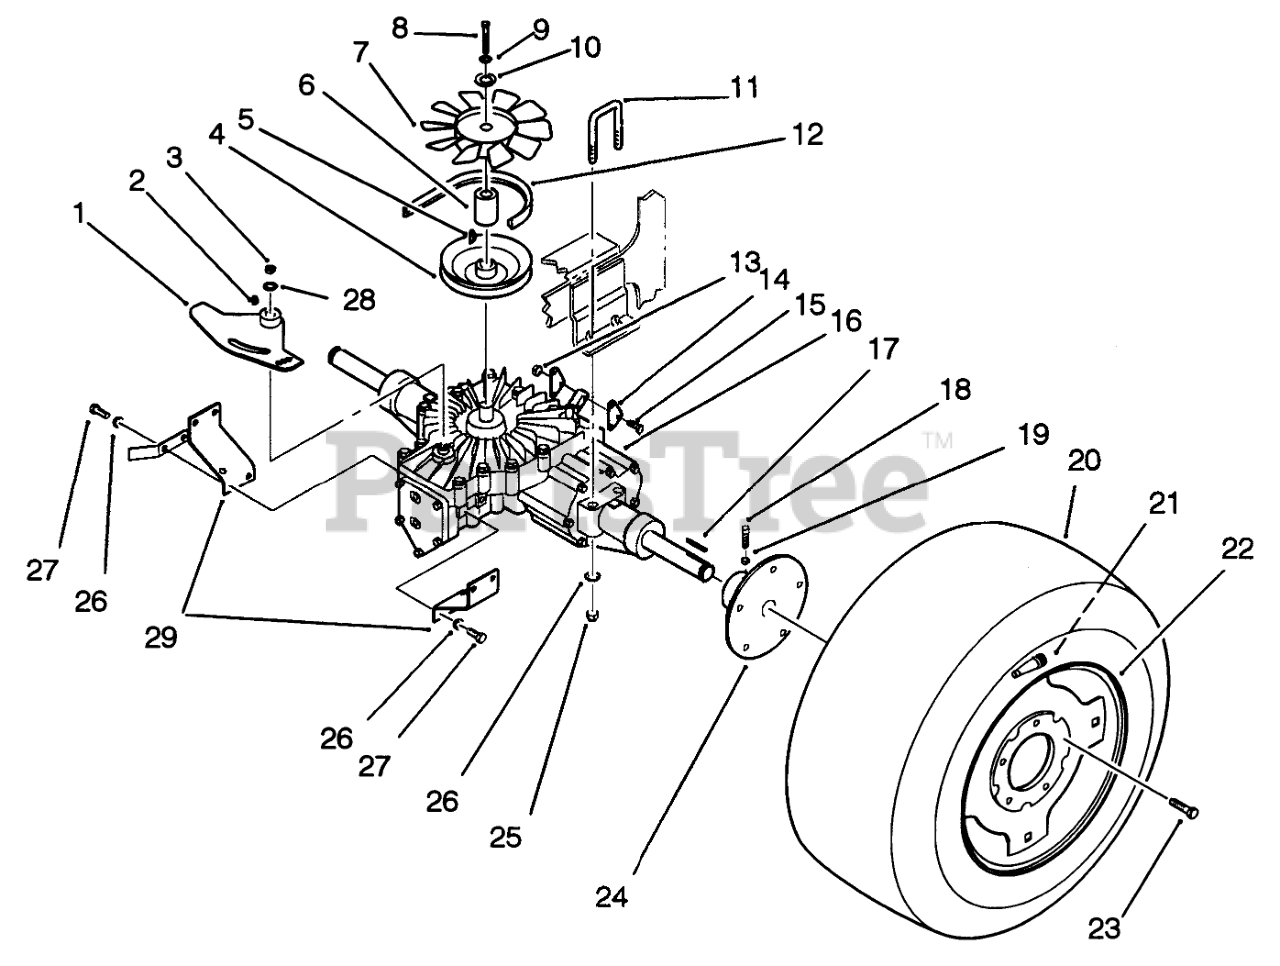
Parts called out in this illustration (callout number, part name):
1	WLDMT-CONTROL ARM
2	KEY WOODR 1/8X1/2 DI
3	Nut
4	PULLEY-TRANS
5	HARD HI PRO KEY
6	SPACER
7	FAN-7"
8	Screw
9	WASHER-LOCK
10	WASHER
11	U-BOLT
12	BELT-V
13	NUT-LOCK, NI
14	BRACKET
15	SCREW-HH
16	751-TRANSAXLE
17	Key
18	SCREW-SET, SQH
19	NUT-JAM
20	TIRE
21	VALVE
22	WHEEL
23	Lug Nut
24	Hub-Rear
25	NUT-LOCK, NI
26	WASHER-FLAT
27	SCREW-HH
28	Washer
29	BRACKET R
